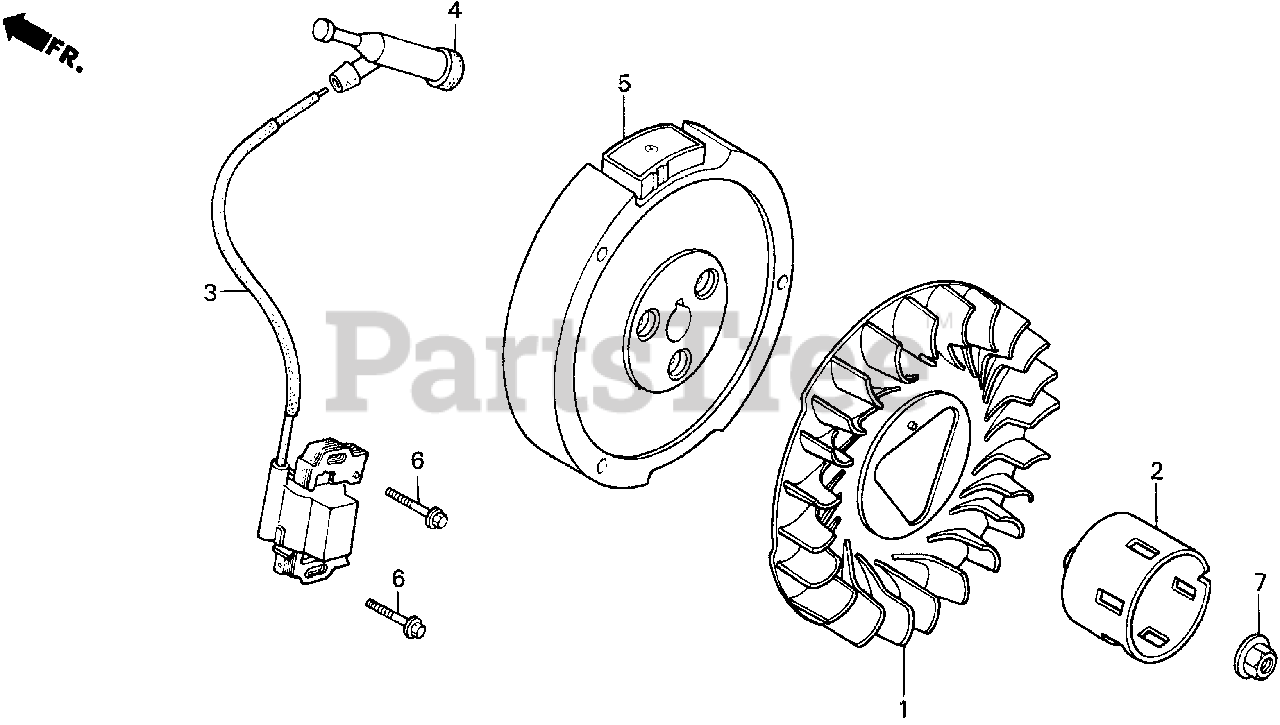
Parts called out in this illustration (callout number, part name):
1	FAN, COOLING
2	PULLEY, STARTER
3	COIL ASSY., IGNITION
4	CAP ASSY., NOISE SUPPRESSOR
5	FLYWHEEL
6	BOLT, FLANGE (6X28)
7	NUT, SPECIAL (16MM) (1)
